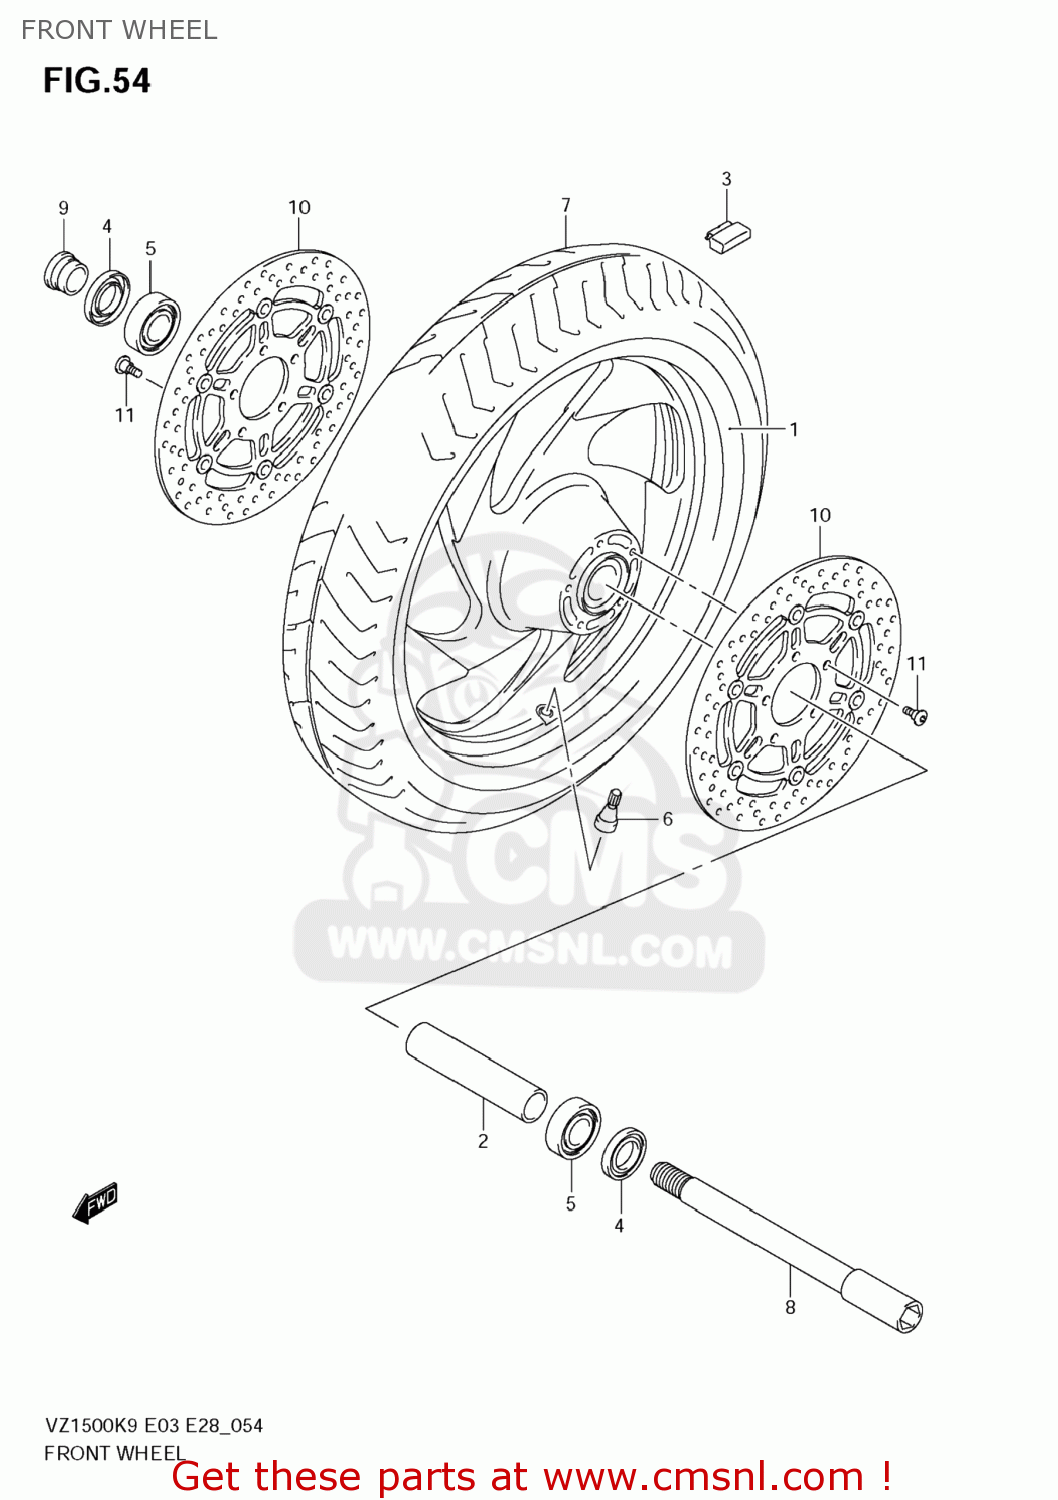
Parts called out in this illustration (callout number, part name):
1	WHEEL,FR(18M/CXMT3.50)
2	SPACER,FR WHEEL BEARING
3	BALANCER,WHEEL(10G)
4	SEAL,OIL(32X52X7)
5	BEARING(25X52X15)
6	VALVE ASSY,WHEEL RIM(TR412)
7	TIRE,FR
8	AXLE,FR
9	SPACER,FR AXLE,L
10	DISC,FR BRAKE
11	BOLT(8X21)
